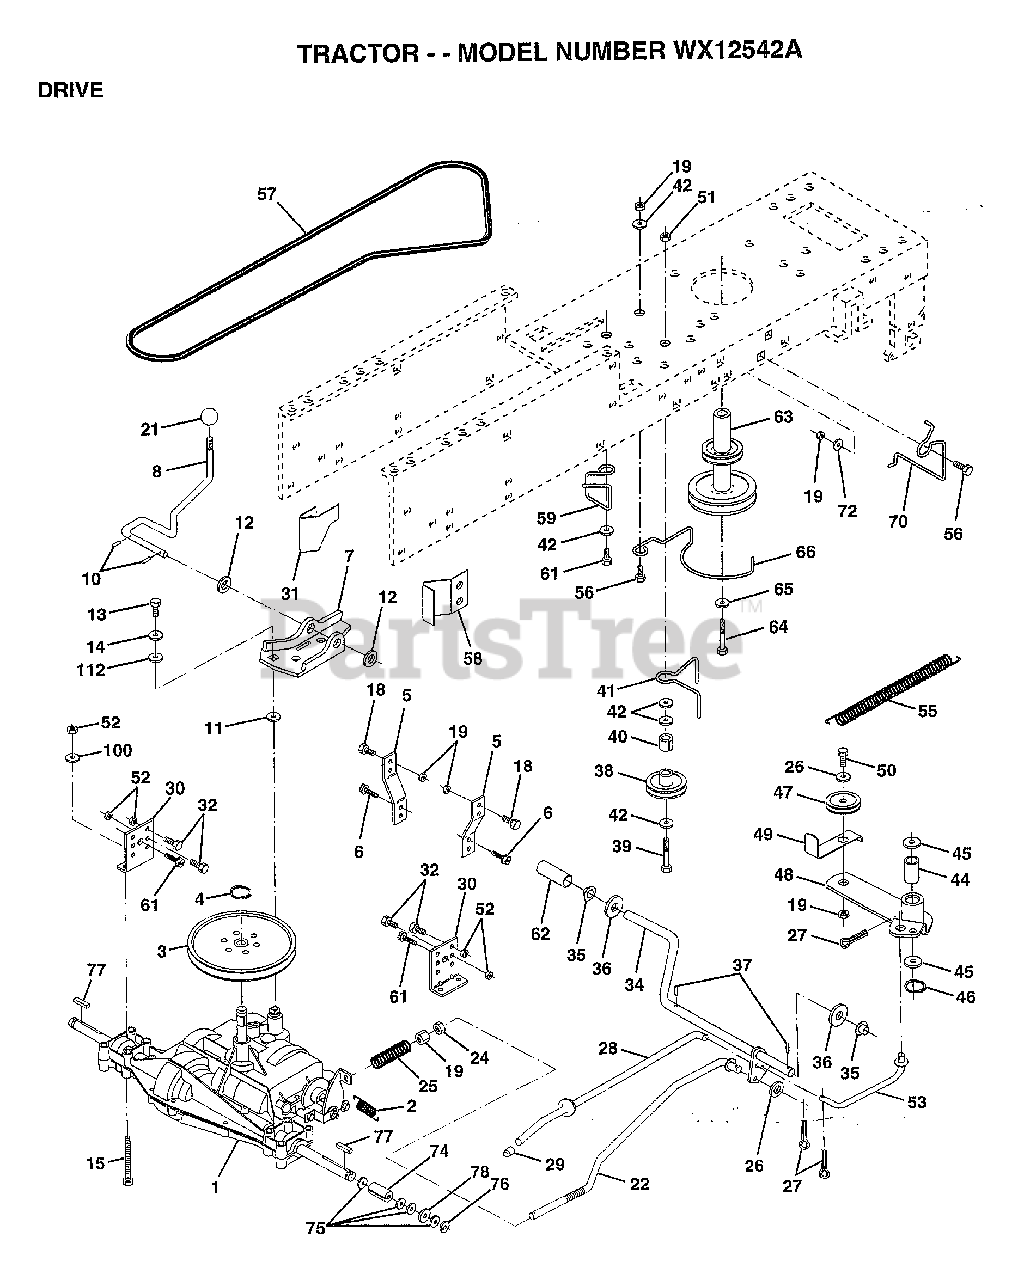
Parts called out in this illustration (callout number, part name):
2	SPRING.BRAKE.RETU
3	PULLEY TRANS
5	STRAP TORQUE
6	SCREW
8	SHIFT ROD
10	PIN COTTER 1/8
11	WASH-SHFT PLT LT
12	WASHER
13	BOLT.1/4-28.W/PAT
14	LOCKWASHER
15	BOLT HEX
18	BOLT
19	NUT
21	KNOB T (1/2-HOLE)
22	BRAKE ROD
24	NUT
25	SPRING, BRAKE ROD
26	WASHER
27	COTTER PIN
28	ROD.BRAKE.PARK.LT
29	PLUNGER CAP T
30	TRANSAXLE MTG BKT
31	"KEEPER,BELT LH T"
32	BOLT
34	SHAFT.PEDAL.FOOT
35	NYLON BEARING
36	WASHER LT
38	PULLEY.IDLER.FLAT
39	BOLT
40	SPACER T
41	BELT KEEPER LT
42	WASHER
44	"LY, BEARING"
45	WASHER LT
46	KLIP RING
48	ARM IDLER
49	RETAIN BELT
53	"LINK, CLUTCH T"
55	"SPRING, RETURN LT"
58	"KEEPER,BELT RH T"
59	KEEPER BELT CNTSP
61	SCREW
62	PEDAL COVER T
63	PULLEY.ENGINE
64	BOLT
65	LOCKWASHER
66	KEEPER.BELT.ENG.L
70	KEEPER BELT ENG
72	WASHER
74	SPACER LT
75	WASHER
76	E-RING LT
77	SQUARE KEY
78	WASHER
100	WASHER M
112	WASHER LT
